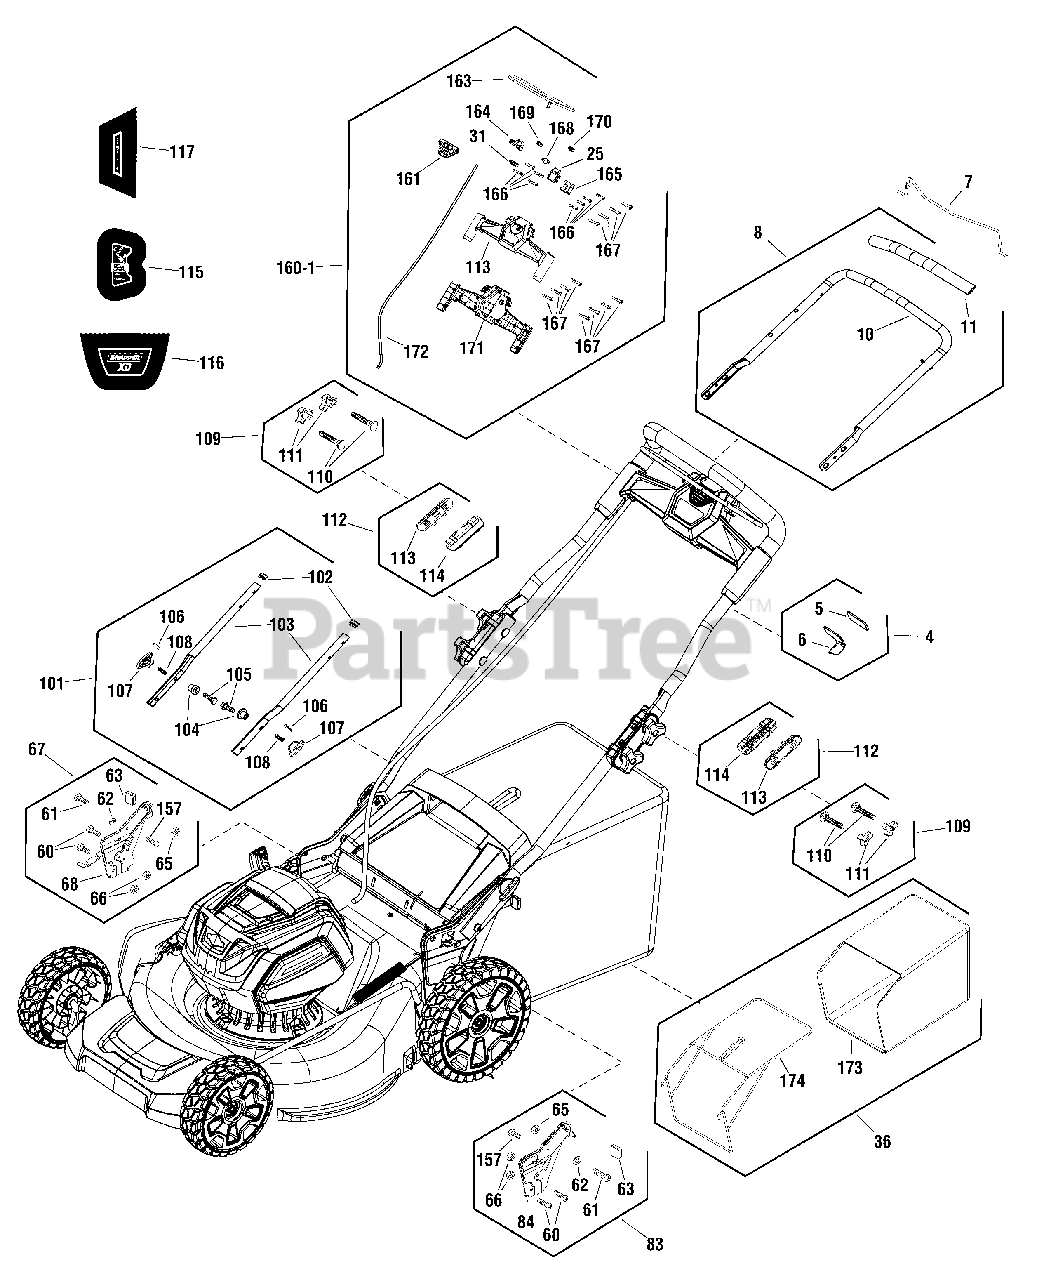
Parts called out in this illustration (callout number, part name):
4	KIT, STOP
5	SPONGE
6	STOP
7	KIT, LEVER
8	KIT, UPPER HANDLE, EU
10	UPPER HANDLE
11	SPONGE
25	SWITCH
31	CLAMP
36	KIT, GRASS BAGGER
60	BOLT
61	BOLT
62	GASKET
63	BUMPER
65	NUT
66	NUT
67	KIT, RIGHT BRACKET
68	HEIGHT ADJUST, RIGHT
83	KIT, LEFT BRACKET
84	LEFT HEIGHT ADJUST
101	KIT, LOWER HANDLE
102	TUBE CAP
103	HANDLE, LOWER
104	BUSHING
105	SCREW
106	PIN
107	KNOB
108	SPRING
109	KIT, HARDWARE
110	BOLT
111	KNOB
112	KIT, BOX, FIXED
113	BRACKET
113	TOP COVER
114	BRACKET
115	DECAL, START
116	DECAL, XD SHROUD
117	DECAL, CHARGER INDICATOR
157	SCREW
160-1	KIT, SWITCH BOX COMPONENT, EU
161	KEY, START
163	BAR
164	BLOCK
165	INSERT
166	SCREW
167	SCREW
168	CLAMP
169	SPRING
170	SPRING
171	BOTTOM COVER
172	CABLE
173	GRASS CATCHING BAG
174	FRAME
